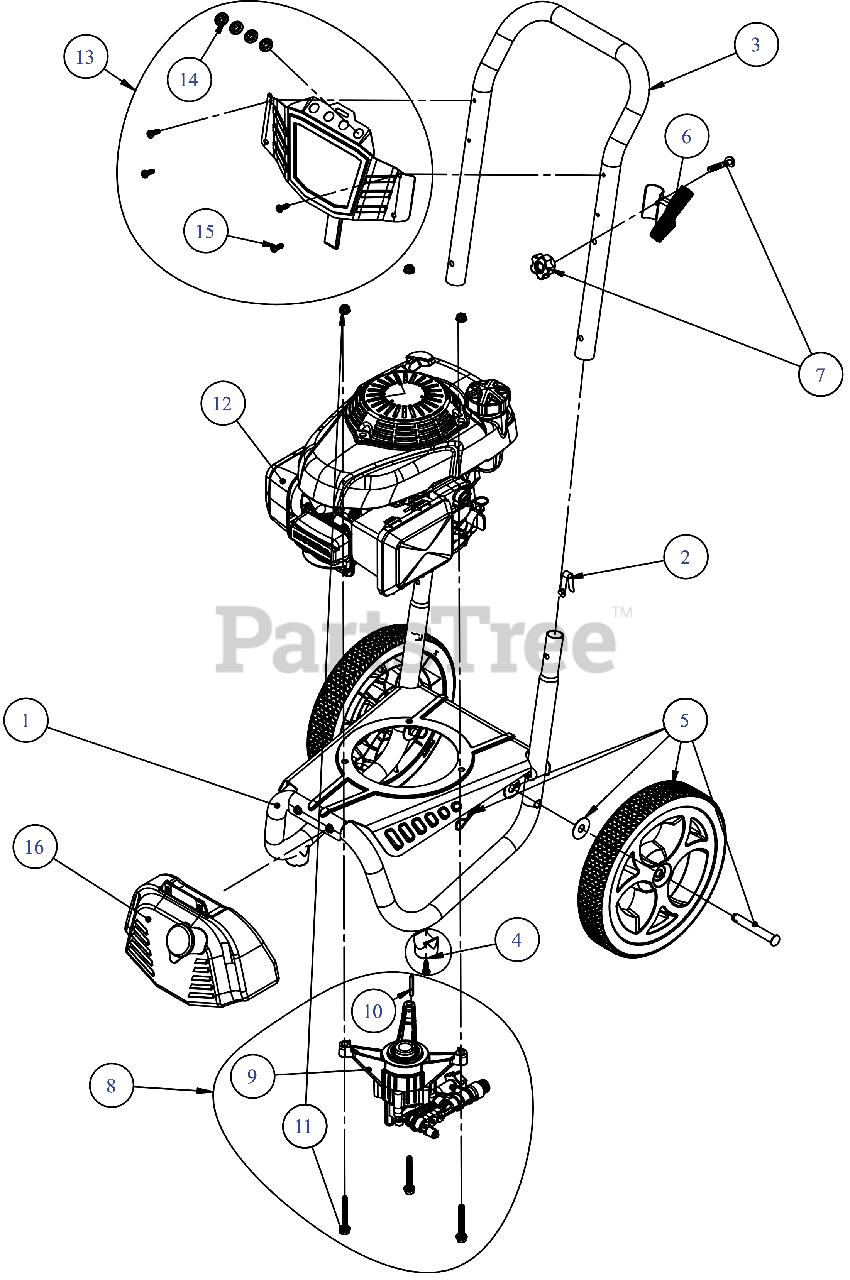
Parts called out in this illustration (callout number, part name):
1	FRAME BASE (YELLOW)
2	HANDLE SNAP BUTTON
3	UPPER HANDLE
4	FOOT PAD KIT
5	WHEEL KIT-12"
6	SPRAY GUN HOLDER
7	KNOB-HANDLE MTG
8	PUMP ASSEMBLY-SVC 51AL24
9	PUMP
10	SHAFT KEY (3/16x3/16x1.5)
11	HARDWARE KIT-PUMP MTG
12	ENGINE SVC ASSY W/ LABELS
13	DASHBOARD PANEL (W/LABEL CC 3024H)
14	SPRAY NOZZLE HOLDER
15	DASHBOARD SCREW
16	SOAP TANK (W/LBL)
